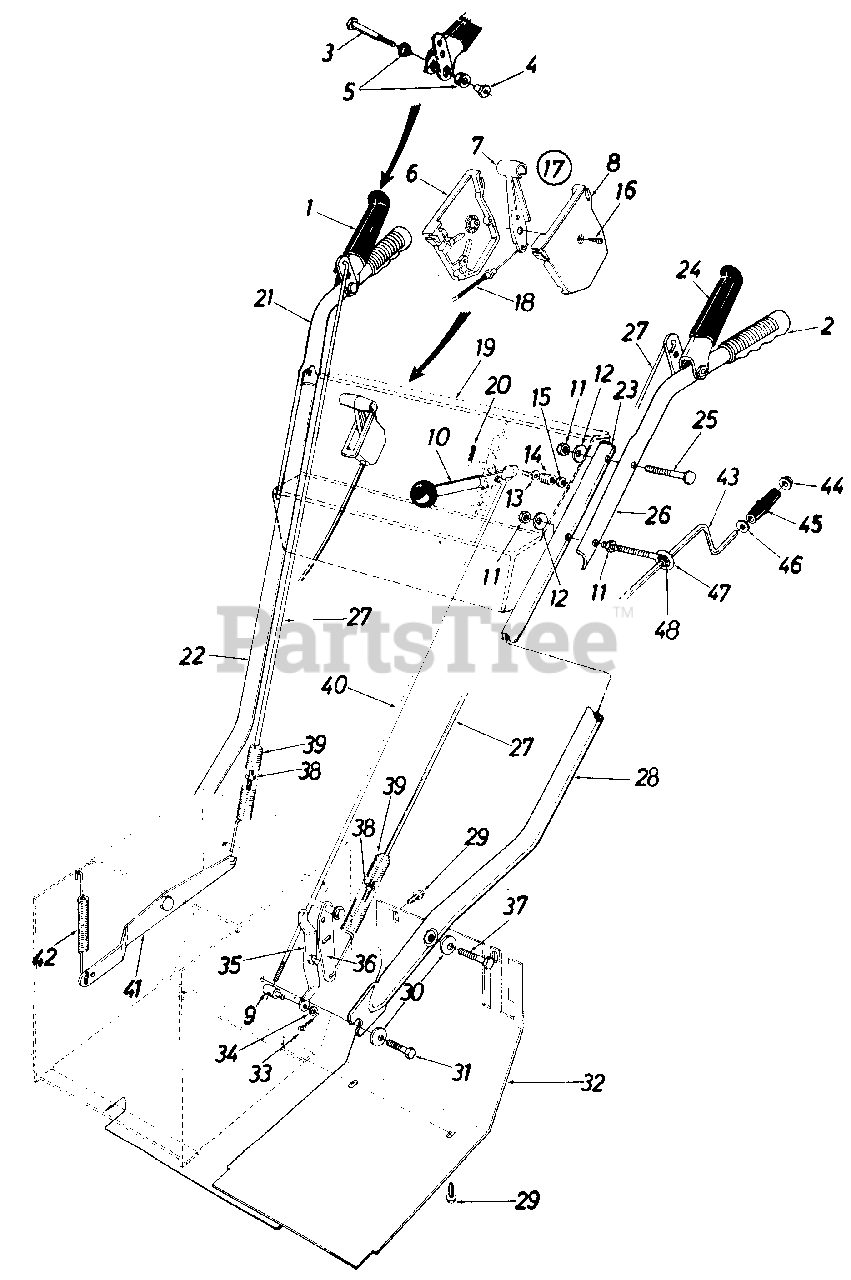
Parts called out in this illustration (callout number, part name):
1	Clutch Grip Ass'y. - R.H.
2	Grip
3	Shoulder Bolt .374 Dia. x 1.53" Lg.
4	Shld. Nut 1/4-20 Thd.
5	Hex Flange Plastic Bearing .38" I.D.
9	Adjustment Ferrule
10	Shift Handle Ass'y.
11	Hex Nut 5/16-18 Thd.
12	Bell-Wash. .34" I.D. x .88" O.D.
13	Bell-Wash. .40" I.D. x .88" O.D.
14	Compression Spring
15	Hex Ins. L-Nut 3/8-24 Thd.
17	Throttle Control Box Ass'y.
18	Throttle Control Wire
19	Handle Panel Ass'y.
20	Int. Cotter Pin 5/16" Dia.
21	Upper Handle - R.H.
22	Lower Handle - R.H.
23	Plastic Plug
24	Clutch Grip Ass'y. - L.H.
25	Carriage Bolt 5/16-18 x 2.0" Lg.
26	Upper Handle - L.H.
27	Lockout Rod
28	Lower Handle - L.H.
29	Hex Wash. Hd. Self-Tap Scr. 5/16-24 x .50" Lg.
30	Bell-Wash. .40" I.D. x .88" O.D.
31	Pilot Hex Scr. 3/8-16 x .88" Lg.
32	Frame Cover
33	Cotter Pin, 3/32" Dia.
34	Fl-Wash. .345 I.D. x .62 O.D. x .06
35	Shifting Linkage Brkt.
36	Drive Clutch Brkt. Ass'y.
37	Hex Bolt 3/8-16 x 2.0" Lg.
38	Hex Ins. L-Nut 1/4-20 Thd.
39	Ext. Spring .75" O.D. x 5" Lg.
40	Shift Rod
41	Auger Clutch Brkt.
42	Ext. Spring .38" O.D. x 3.18" Lg.
43	Chute Crank Ass'y.
44	Push Nut 3/8" Rod
45	Knob 3/8" Rod
46	Fl-Wash. .40" I.D. x .62" O.D.
47	Eyebolt 5/16-18 x 5.0" Lg.
48	Grommet
